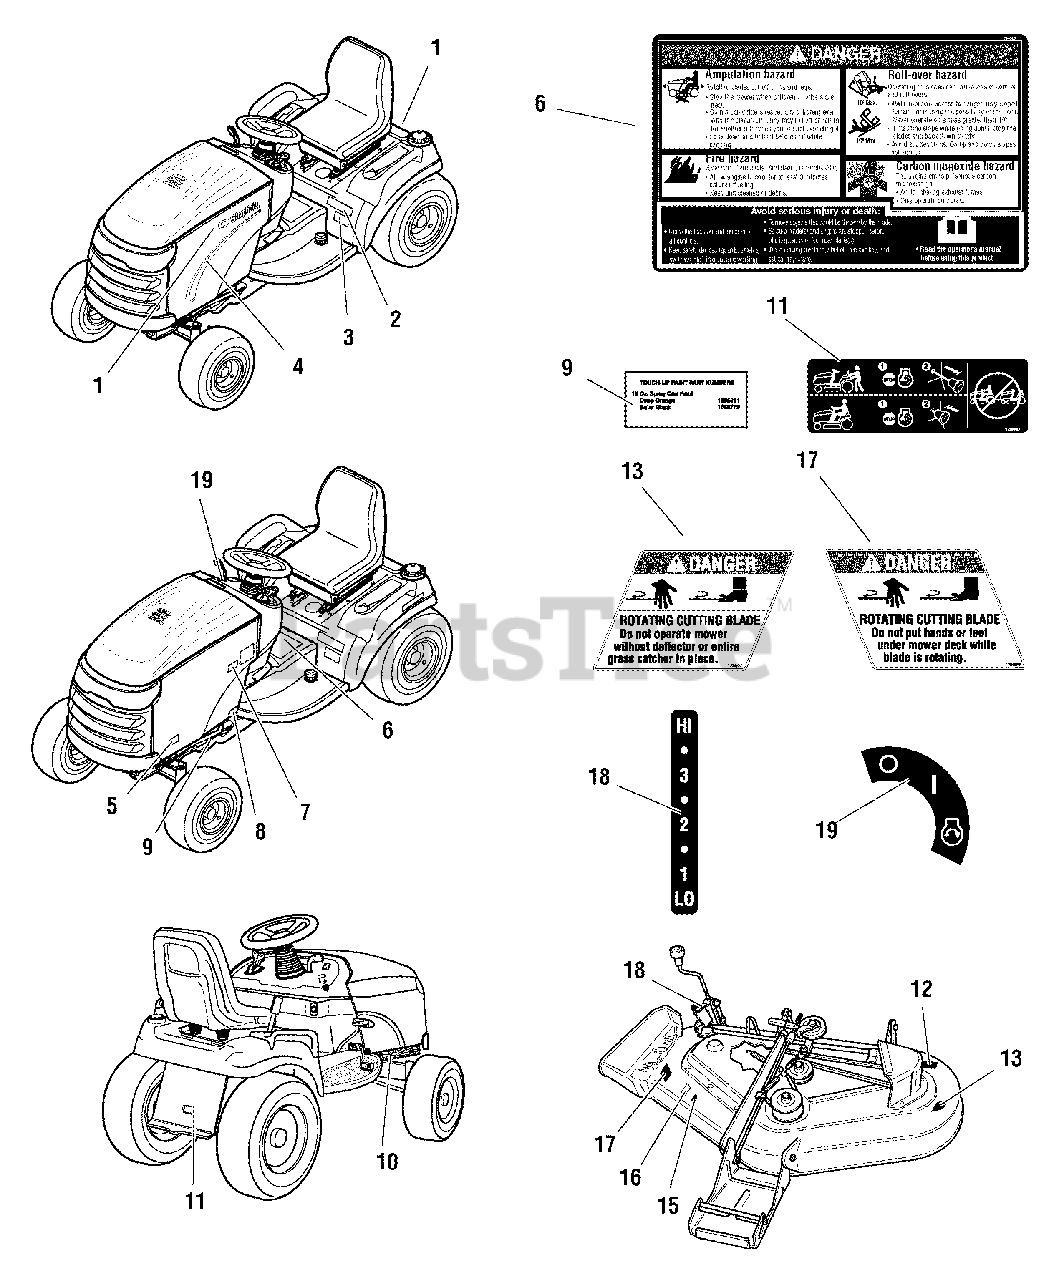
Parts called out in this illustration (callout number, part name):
1	DECAL, Simplicity Silver & Blue w/Icon
2	DECAL, Conquest, Silver & Blue
3	DECAL, 23HP Silver on Clear
4	DECAL, Hood Stripe R.H. SMI Blue & Silver
4	DECAL, Hood Stripe L.H. SMI Blue & Silver
6	DECAL, Tunnel Cover Danger Slopes, Blades
7	DECAL, Touch Up Paint
8	STICKER, Protection
9	DECAL, I.D. Plate
10	DECAL, Patent
11	DECAL, Transmission Release Valve
12	DECAL, I.D. Plate
13	DECAL, Danger Do Not Operate w/o Deflector
15	DECAL, OPEI Certified
16	DECAL, 50" Silver on Black w/Stripe
17	DECAL, Danger Do Not Put Hand/Feet In Mower
18	DECAL, 1 2 3 4 5 6, Height of Cut White/Black
19	DECAL, Ignition Switch Symbols
